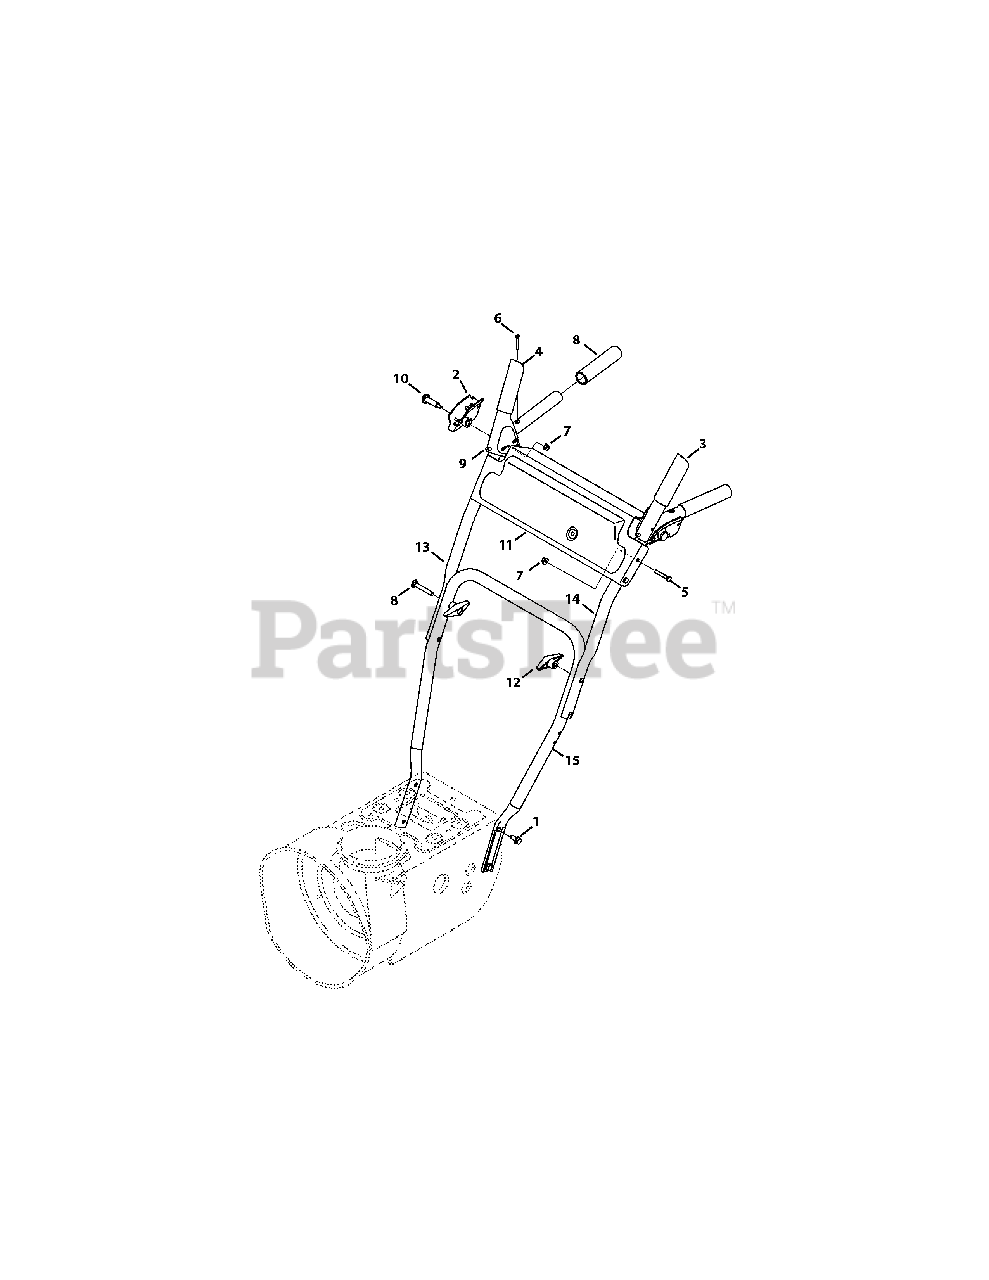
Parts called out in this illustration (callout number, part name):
1	Taptite Screw, 5/16-18 x .750
2	Clutch Lock Handle Assembly, LH
2	Clutch Lock Handle Assembly, RH
3	Engagement Assembly, LH
4	Engagement Assembly, RH
5	Hex Head Screw, 1/4-20 x 1.50
6	Machine Screw, #10-24 x 1.375
7	Flange Lock Nut, 1/4-20
8	Grip, 1.0 ID x 5.0 LG
9	Rubber Bumper, .62 OD x .22 Thick
10	Shoulder Screw, .437 x 1.345 x 1/4-20
11	Handle Panel
12	Wing Knob
13	Upper RH Handle
14	Upper LH Handle
15	Lower Handle
